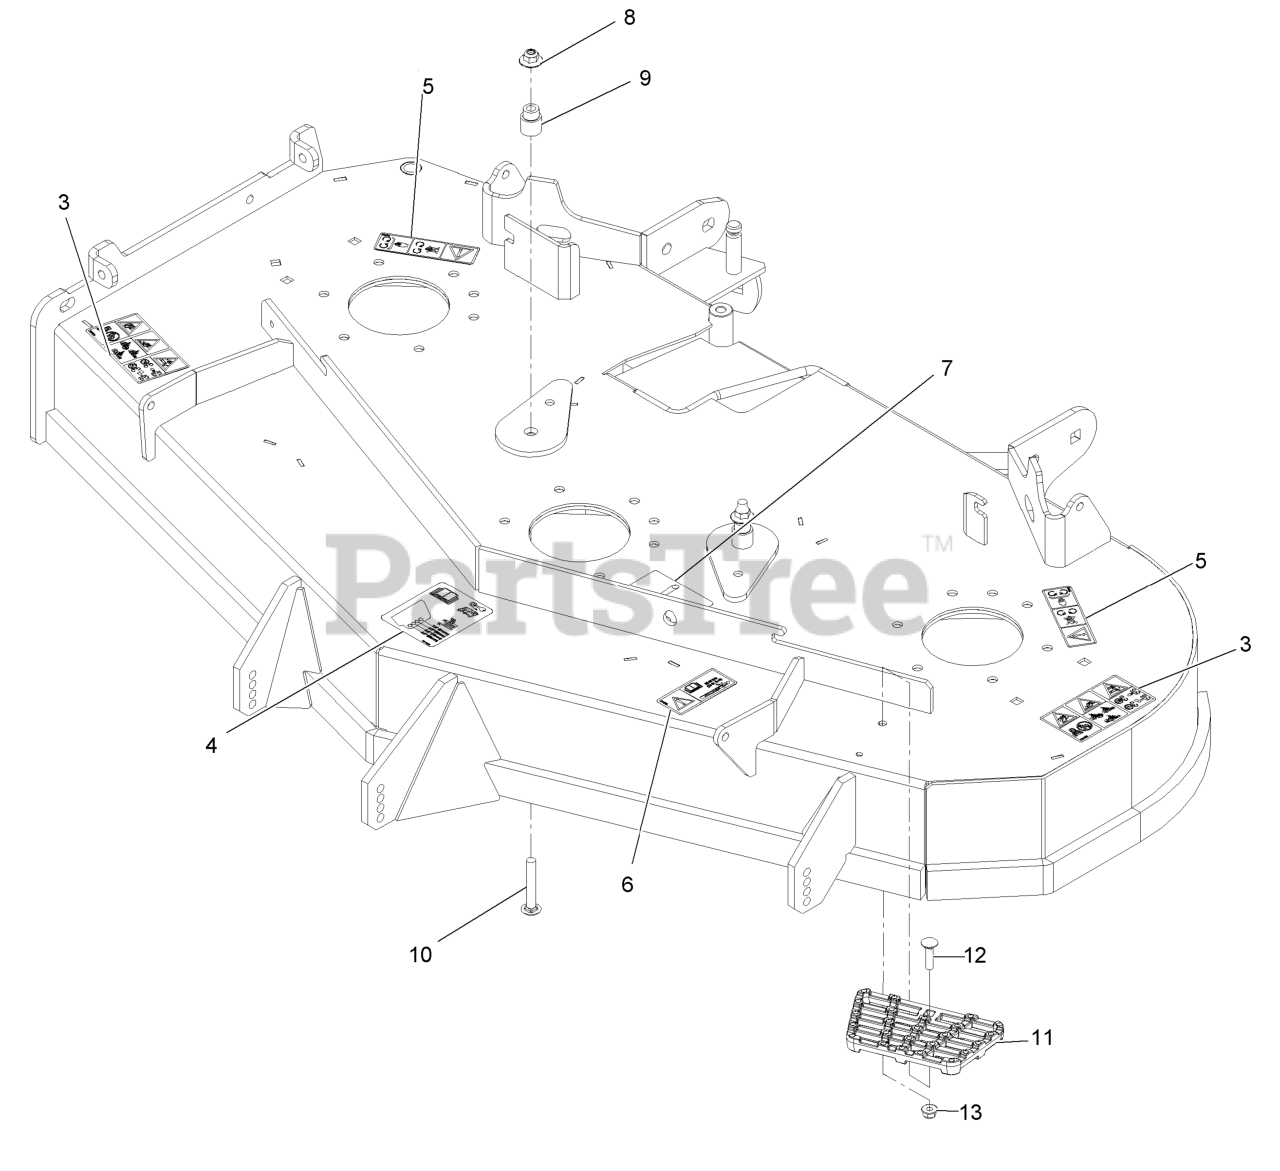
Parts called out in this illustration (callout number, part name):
3	DECAL-DANGER THROWN OBJECTS
4	DECAL-ROLLER, ANTI-SCALP
5	DECAL-COVER, MISSING
6	DECAL-BOLT TORQUE
7	DECAL-BELT ROUTING
8	Nut-Nyloc 3/8-16 Flg
9	BUSHING-IDLER
10	SCREW-CARR
11	STEP-DECK
12	Bolt-Carriage 5/16-18 X 1 1/4
13	NUT-HF, NI
